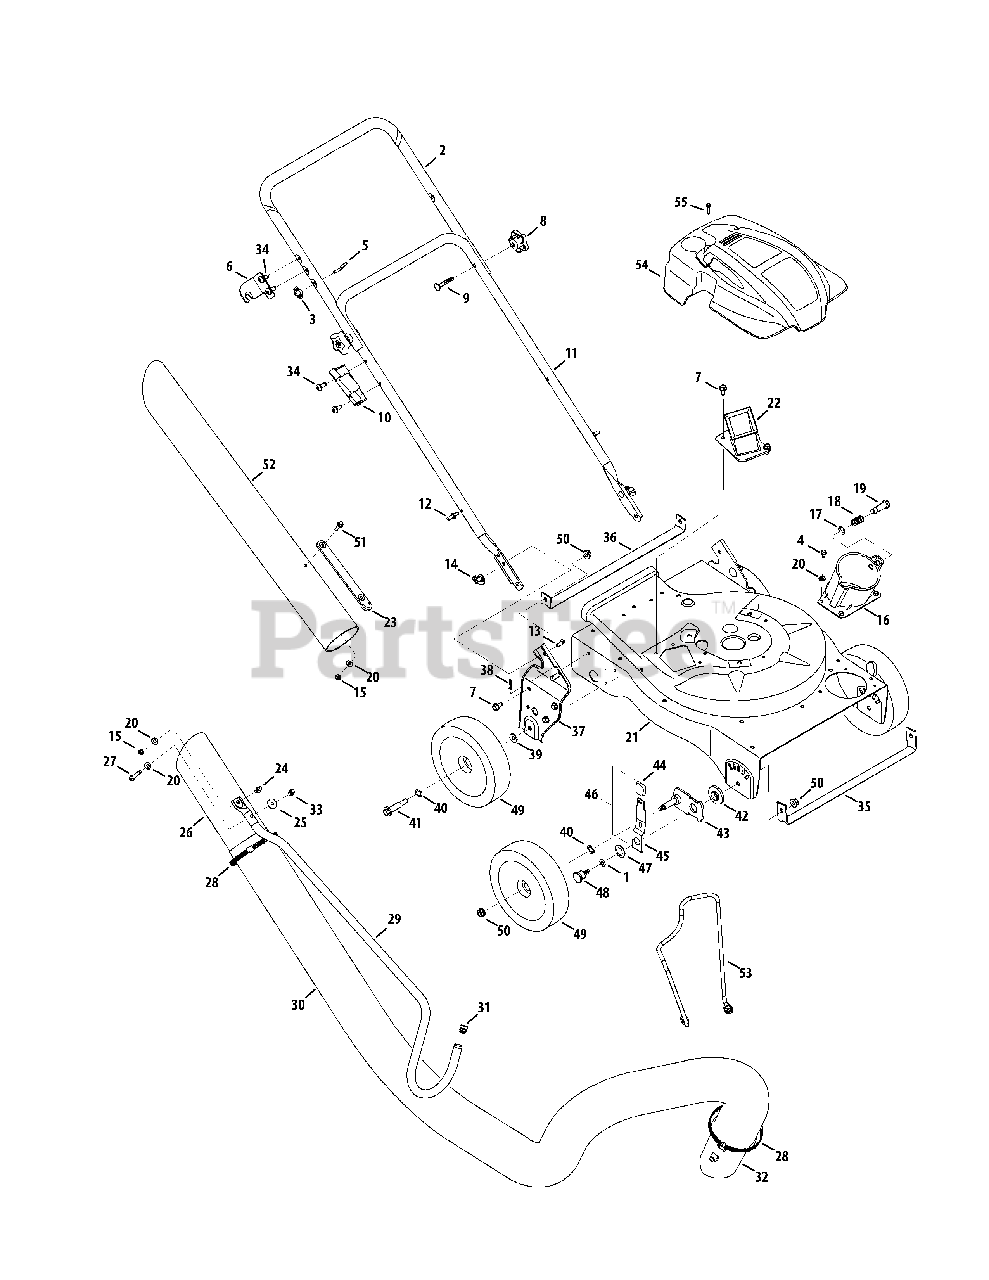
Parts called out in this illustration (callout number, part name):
1	Thrust Washer.375 ID x.70 OD
4	Screw, 1/4-20 x.500
6	Upper Handle Bracket
7	Hex Cap Screw 5/16-12 x.750
9	Carriage Bolt
10	Nozzle Handle Clip
13	Carriage Screw 1/4-20 x.75
14	Wing Nut 1/4-20
15	Hex Lock Nut, 1/4-20
16	Hose Base Adapter Assembly
17	E Ring.500 Dia
18	Compression Spring
19	Clevis Pin
20	Flat Washer.271 ID x.630 OD
21	Upper Flail Housing
22	Chipper Chute Assembly
23	Chute Strap
26	Hose Nozzle
27	Hex Cap Screw 1/4-20 x 2.625
28	Adjustment Clamp
30	Vacuum Hose
31	Handle Plug
32	Hose Adapter
32	Hose Adapter (173 CC)
33	Cap Lock Nut, 1/4-20
34	TT Screw, 5/16-18 x .750
35	Front Wheel Support Brace
36	Rear Wheel Support Brace
37	Handle Bracket Ass’y RH
37	Handle Brkt Ass’y LH
38	Cotter Pin
39	Bell Washer.401 ID x.870 OD
40	Wave Washer.531 ID x.781 OD
41	Shoulder Screw 3/8-16
42	Height Adjustment Bearing
43	Pivot Arm Assembly
44	Height Adjustment Knob
45	Spring Lever
46	Height Lever Assembly
47	Bell Washer.760 ID x.25 OD
48	Shoulder Screw,.750 x.500
49	Wheel 8 x 2
50	Flange Lock Nut, 3/8-16
51	Screw, 1/4-20 x .75
52	Hose Extension
53	Tube Holder
54	Engine Shroud
55	Screw, #12-16 x 1.00
